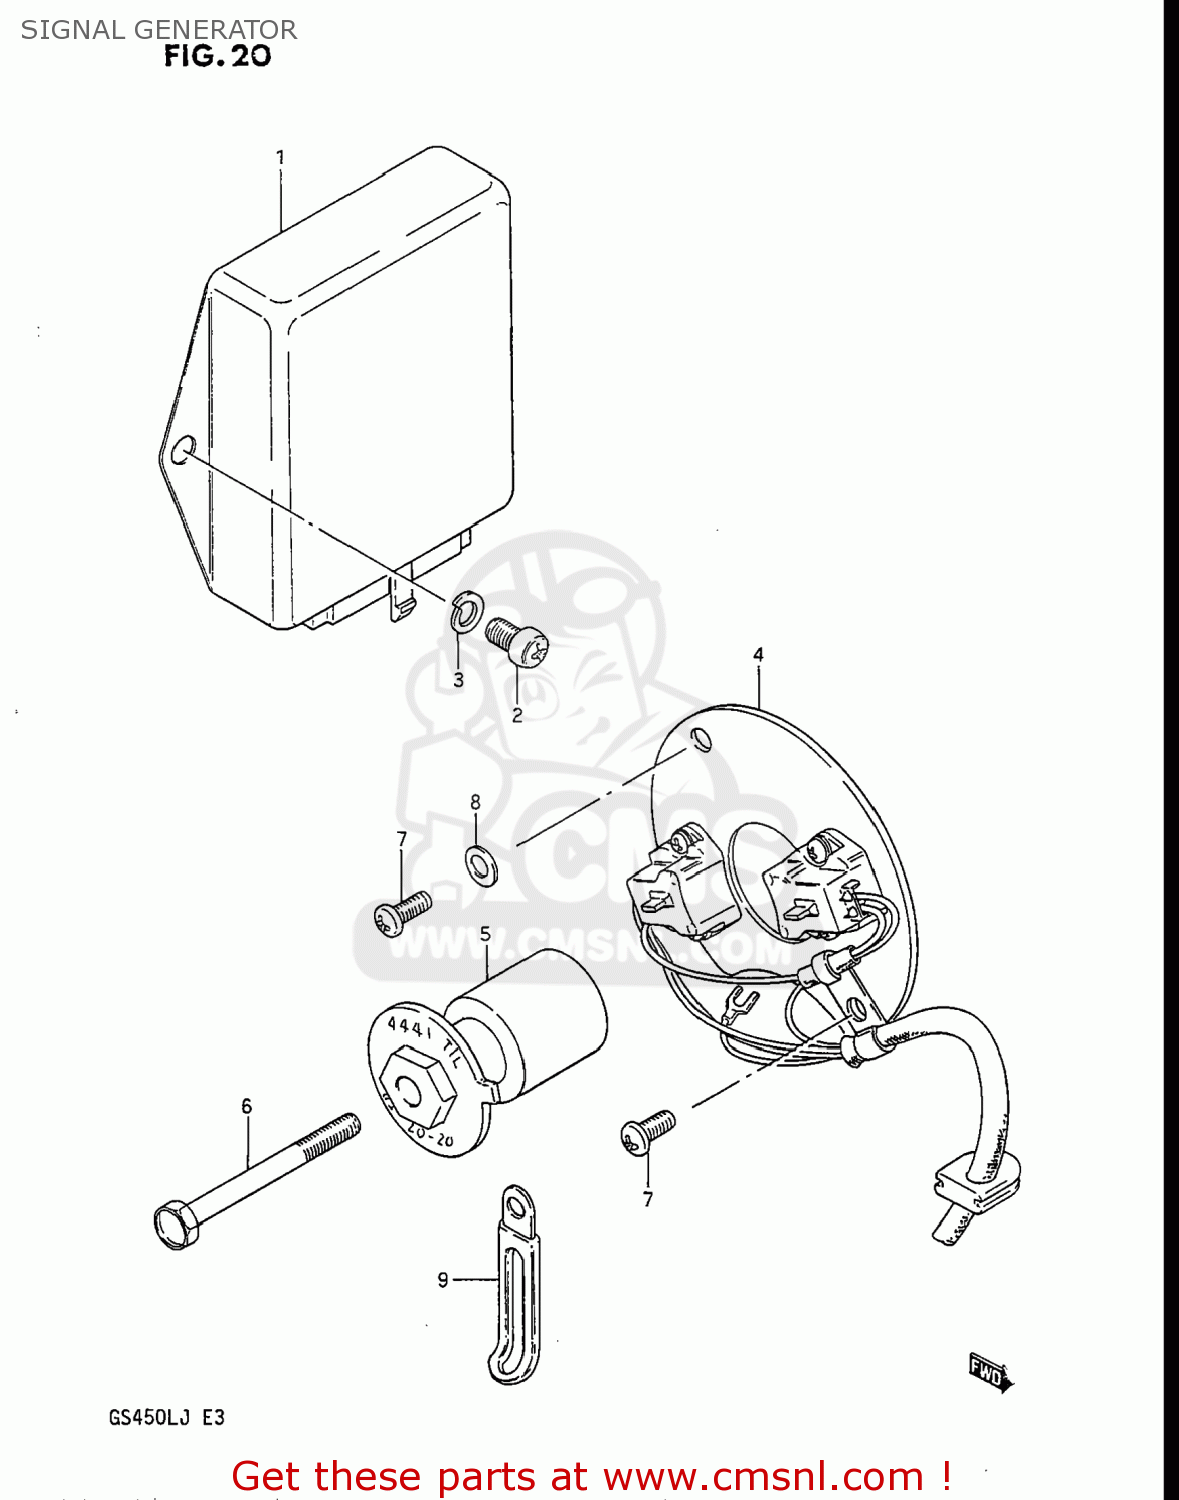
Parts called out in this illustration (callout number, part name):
1	IGNITOR UNIT
2	SCREW
3	WASHER,LOCK
4	SIGNAL GENERATOR ASSY
5	ROTOR,SIGNAL
6	BOLT 6X60
7	SCREW(5X12)
8	WASHER(5.5X10X0.8)
9	CLAMP L:35
